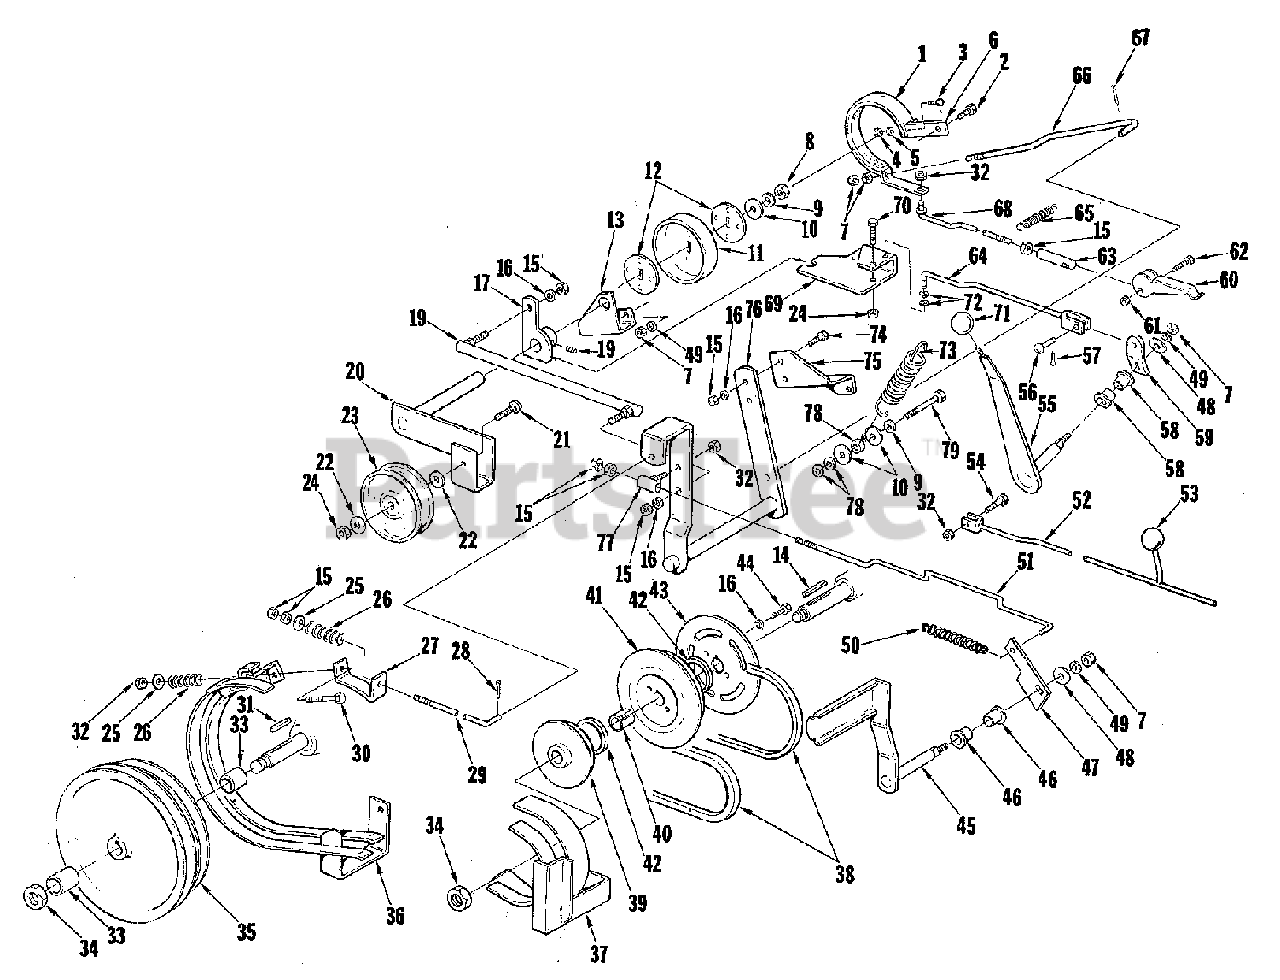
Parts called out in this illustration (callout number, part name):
1	BAND ASSEMBLY, Brake
2	SCREW, Hex Head Cap
3	SCREW, Hex Head Cap, 1/4-20 x 3/4
4	NUT, Hex Fin, 1/4-20
5	WASHER, Lock, 1/4
6	BRACKET, Brake Band
7	NUT, Hex Fin, 3/8-16
8	NUT, Hex Fin, 7/16-14
9	WASHER, Lock
10	WASHER, Flat, 5/16
12	WASHER, Special
13	BEARING, Idler Pivot
14	KEY, Woodruff, #5
15	NUT, Hex Fin, 5/16-18
16	WASHER, Lock, 5/16
17	LEVER ASSEMBLY, Cam Shaft
18	SETSCREW, Hex Socket, 1/4-20 x 1/4
19	JOINT, Ball, Double End
20	ARM ASSEMBLY, Idler
21	CARRIAGE BOLT, 3/8-16 x 1
22	WASHER, Flat
24	NUT, Hex Lock, 3/8-16
25	WASHER, Flat
27	BRAKE, Pulley
29	ROD, Pulley Brake
30	SCREW, Hex Head Cap, 5/16-18 x 2-1/2
32	NUT, Hex Lock, 5/16-18
34	NUT, Lock Jam, 3/4-16
35	SHEAVE, Double
36	RETAINER ASSEMBLY, Rear
37	RETAINER ASSEMBLY
38	BELT, "V", Dual Range Drive
39	PULLEY, Half Outside
40	BEARING, Pulley
41	PULLEY HALF, Center
42	WASHER, Thrust
43	PULLEY, Half Inside
44	SCREW, Hex Head Cap
45	PEDAL ASSEMBLY, Foot
46	BUSHING, Flanged
47	ARM, Foot Pedal
49	WASHER, Lock, 3/8
50	SPRING, Break Pedal
51	ROD, Clutch & Brake
52	ROD, Shift Assembly
53	BALL, Shift Lever
54	SCREW, Hex Head Cap
55	LEVER ASSEMBLY
58	BUSHING, Flanged
59	LINK, Speed Control
60	LEVER, Parking Brake
61	NUT, Hex Lock, 1/4-20
62	SCREW, Hex Head Cap, 1/4-20 x 1-1/4
64	ROD ASSEMBLY, Control
68	ROD ASSEMBLY, Parking Brake
70	SCREW, Hex Head Cap, 3/8-16 x 2
71	BALL, Clutch Lever
72	RING, "E" External
73	SPRING, Tension
74	SCREW, Hex Head Cap, 5/16-18 x 3/4
75	BRACKET, Spring
76	LEVER ASSEMBLY, Pivot
77	GUIDE ASSEMBLY, Rod
79	SCREW, Hex Head Cap, 7/16-14 x 2
